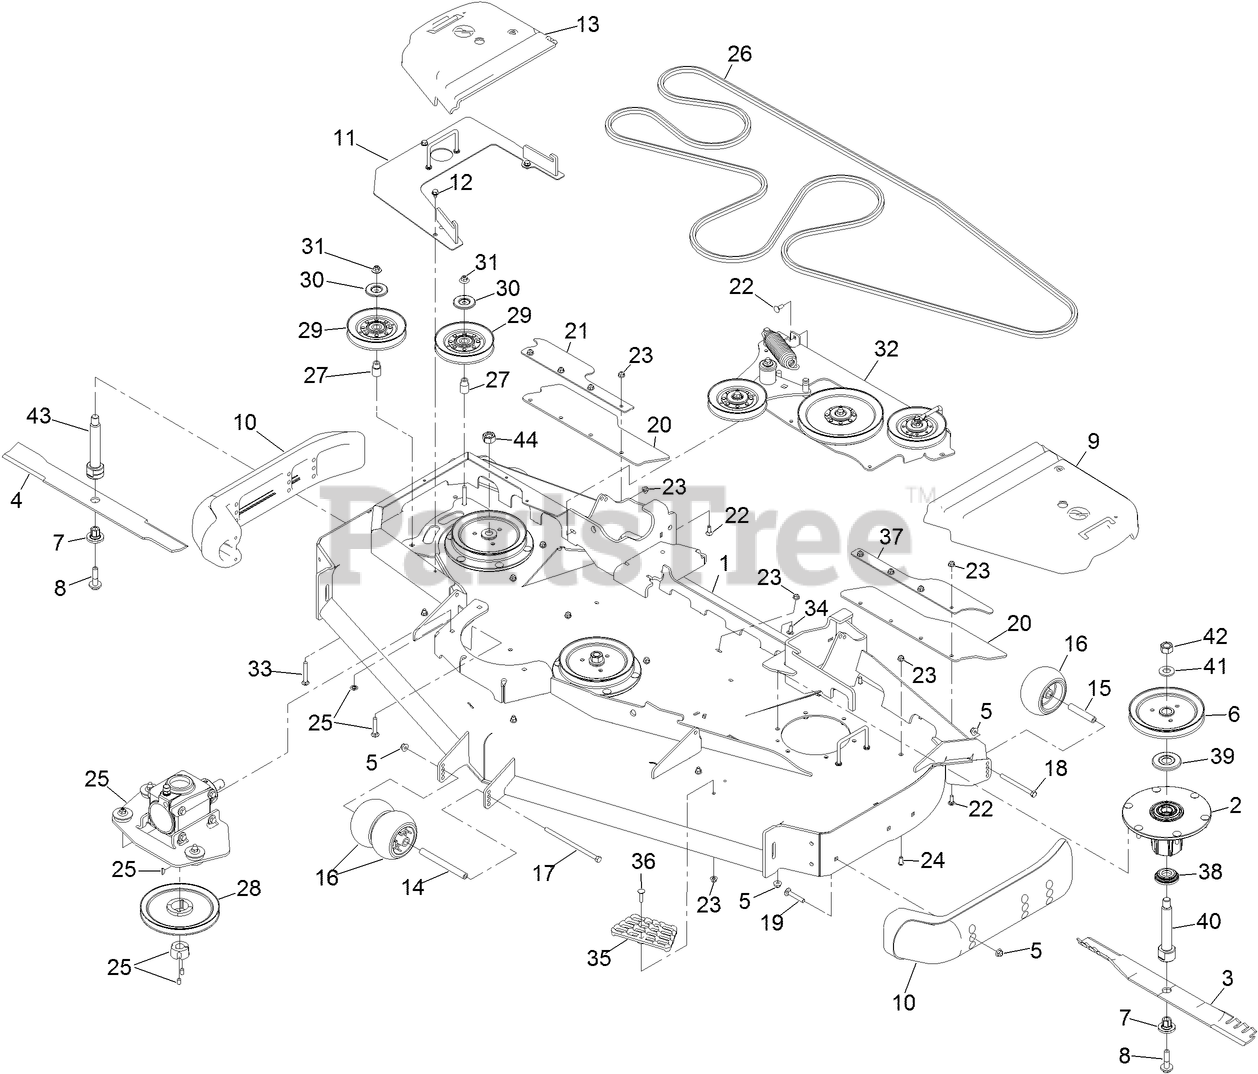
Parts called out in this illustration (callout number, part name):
1	DECK DECAL ASM
2	SPINDLE ASM
3	BLADE-24.50 ATOMIC
4	BLADE-24.50 CR LOW FLOW
5	NUT-HF, NI
6	SHEAVE-DRIVE, BLADE
7	BUSHING-HEX
8	SCREW-SEMS
9	COVER-BELT, LH
10	SKID-BUMPER, DECK
11	COVER-REVERSE DRIVE
12	SCREW
13	COVER-BELT, RH
14	SPACER-WHEEL
15	TUBE-SPANNER
16	ROLLER-SCALP, ANTI
17	SCREW-HH
18	SCREW-HH
19	SCREW-CARR
20	GUARD-TIRE
21	SUPPORT-FLAP, OUTER (RH)
22	SCREW-CARR
23	NUT-HF, NI
24	SCREW-HSBH
25	GEARBOX ASM
26	BELT-BB
27	STANDOFF-IDLER
28	PULLEY
29	IDLER V
30	SHIELD-DUST
31	NUT-FLANGE, NI
32	IDLER MOUNT ASM
33	SCREW-CARR
34	SCREW-CARR
35	STEP-DECK
36	SCREW-CARR
37	SUPPORT-FLAP, OUTER (LH)
38	GUARD-BOTTOM
39	GUARD-BEARING, TOP
40	SHAFT-SPINDLE
41	WASHER
42	NUT-HEX
43	SHAFT-SPINDLE, INT. HEX LH THD
44	NUT-HEX,LH,LOCK
